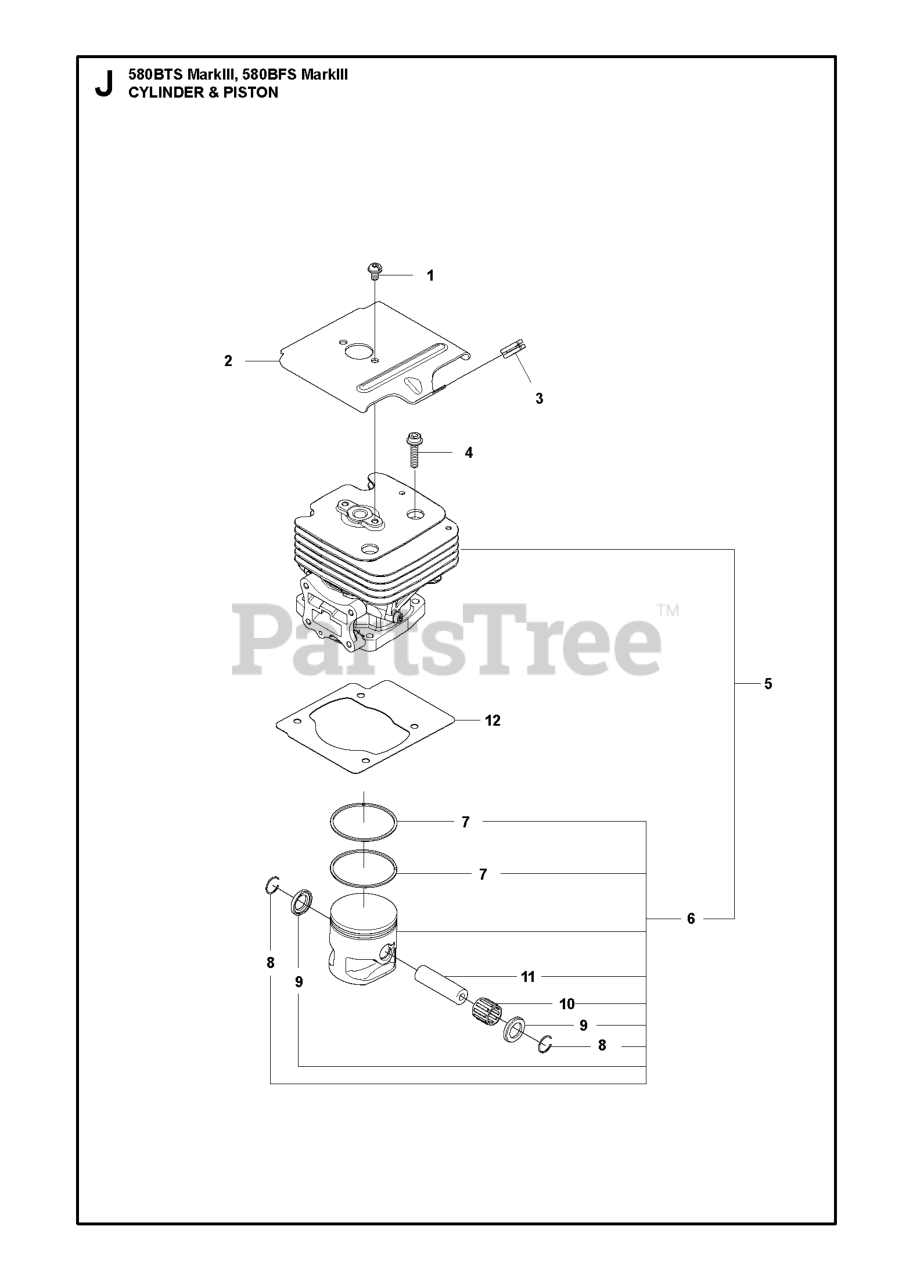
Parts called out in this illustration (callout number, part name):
5	CYLINDER AND PISTON
7	PISTON RING
11	PISTON PIN
